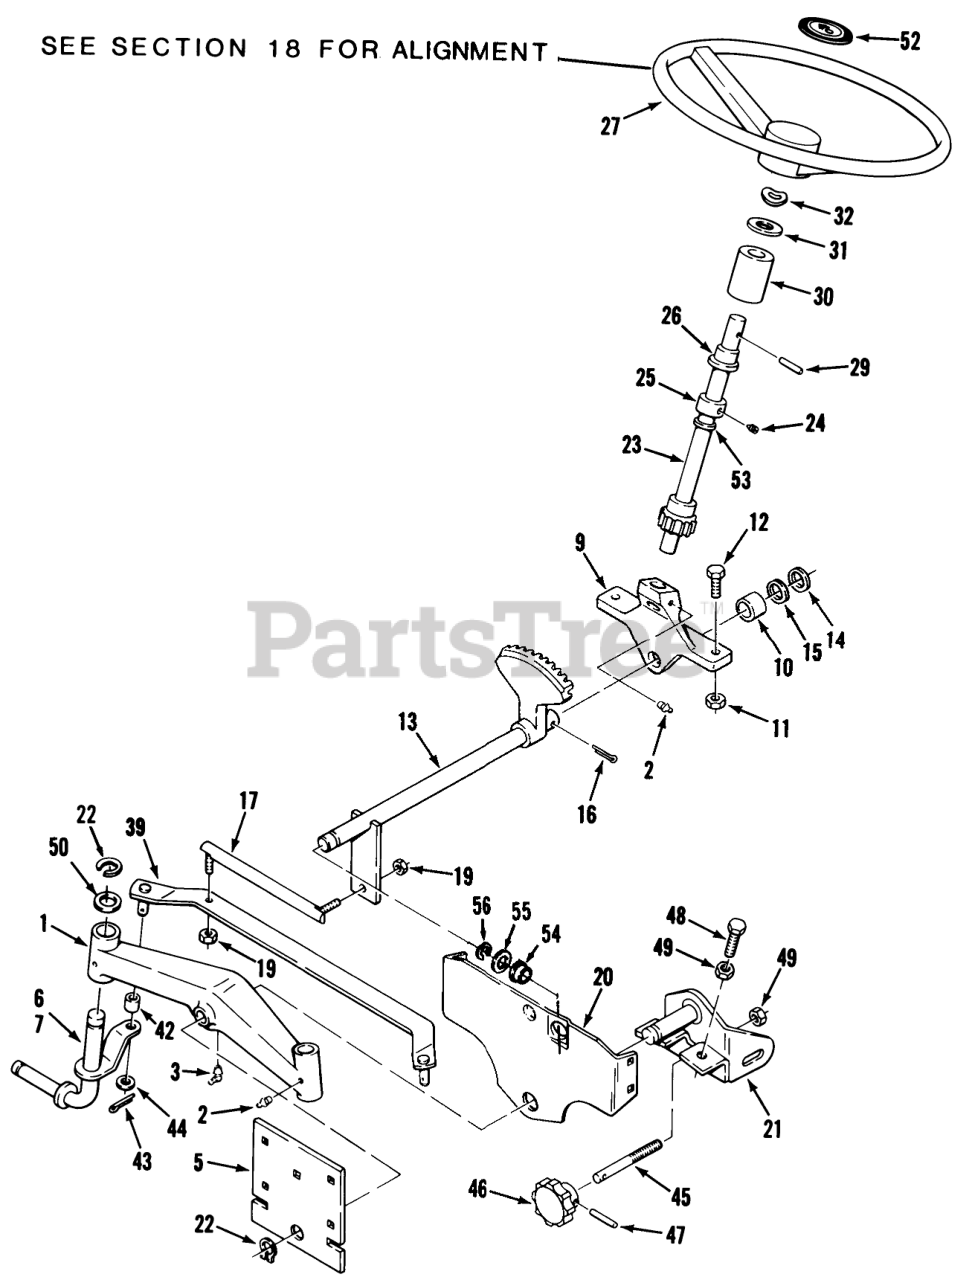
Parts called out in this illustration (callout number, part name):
1	AXLE-FRONT R
2	Zerk
3	FITTING-GREASE
5	PLATE-FRONT AXLE R
6	Front Spindle Assy RH
7	Front Spindle Assy LH
9	Support
10	BEARING-BRONZE
11	NUT
12	BOLT
13	ASSY-STRG SHAFT L B
14	WASHER-SHIM
15	WASHER
16	PIN-4
17	BALL JOINT ASSY L R
19	NUT-6
20	SUPPORT AXLE R
21	ASSY-FRT HANGER R
22	Snap Ring
23	ASSY-STRG SHFT-UP R
24	SCREW-SET
25	Collar
26	BEARING-FLANGED
27	STEERING WH 13" PLAS
27	Steering Wheel 416
29	Pin-Roll
30	TUBE-STEERING
31	WASHER-FLAT
32	WASHER-BOWED
39	ASSY-TIE ROD R
42	SPACER
44	WASHER
45	ROD-ADJUSTING
46	KNOB-ADJUSTMENT
47	PIN-ROLL
48	Bolt
49	NUT-HEX, JAM
50	WASHER
52	INSERT-STEERING WHL
53	RING-RETAINING
54	BUSHING
55	WASHER SPECIAL
56	Ring
